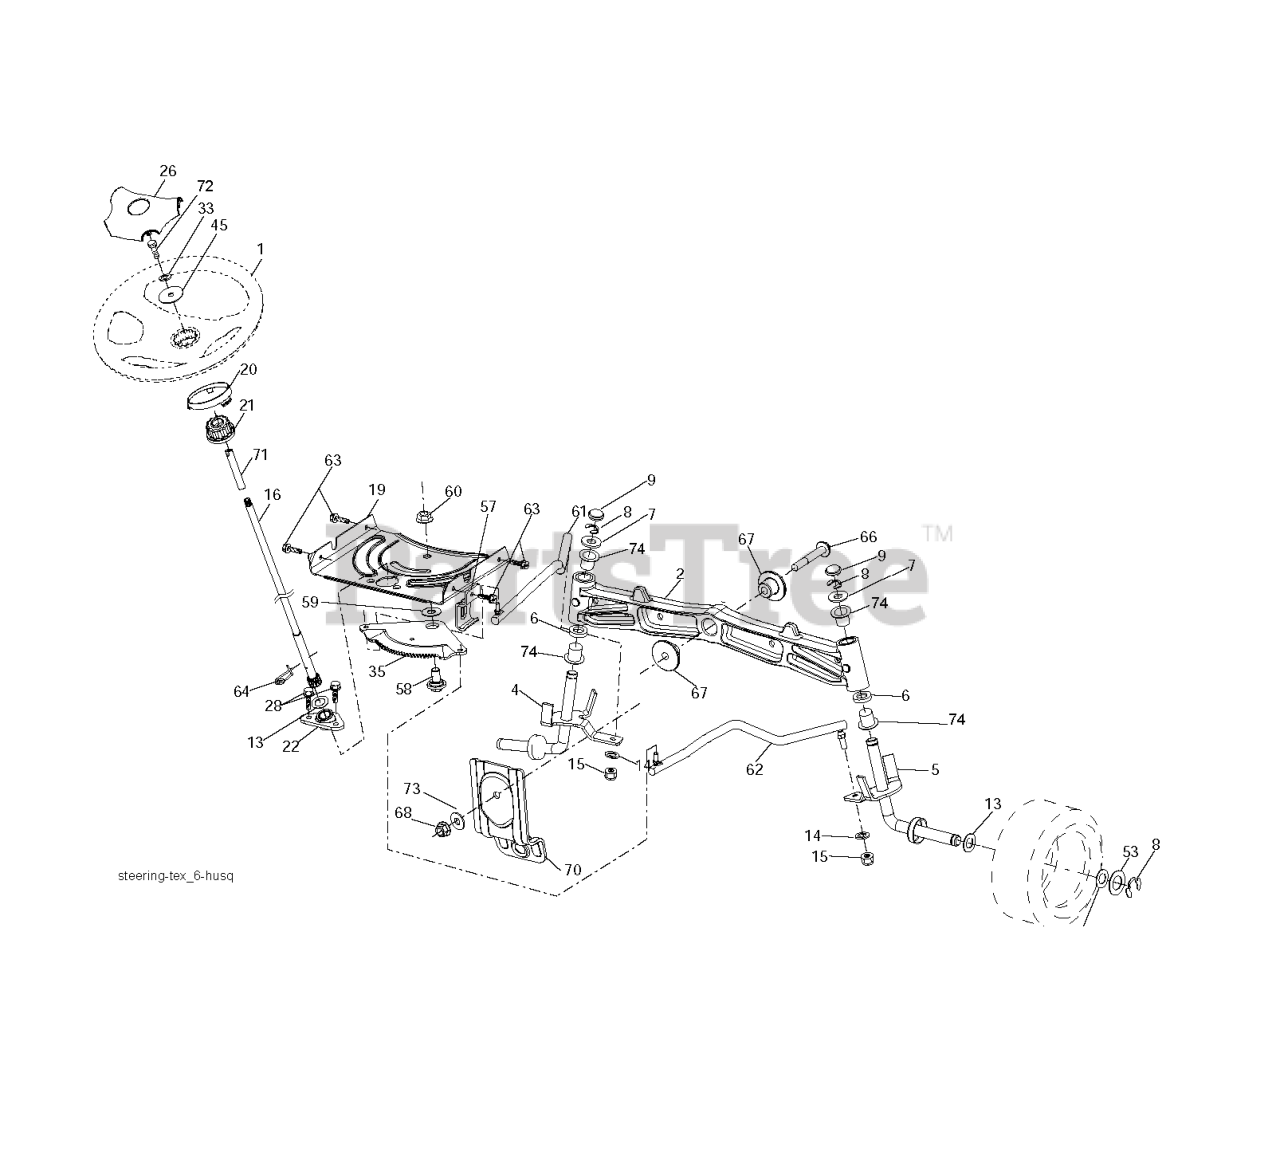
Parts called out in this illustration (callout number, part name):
1	STEERING WHEEL
2	AXLE.HALF.ASM.WELDED
4	SPINDLE.WELDED.LH.15"TEX
5	SPINDLE.WELDED.RH.15"T
6	THRUST WASHER
9	CAP.SPINDLE.BLACK
14	WASHER, LOCK 3/8
15	NUT CROWNLOCK 3/8-24
16	SHAFT STEERING
19	PLATE.STEER.DDL.NLT/NG
20	BOOT, STEERING
21	ADAPTER, WHEEL STNG..
22	BUSHING.ASM.STEERING.A
26	INSERT.CAP.STRG.WH.GRAY
28	SCREW, 3/8-16X3/4
33	WASHER.LOCK.HVY.HLCL.SPR.5/16
35	GEAR.SECTOR.PLATE.DDL.
45	WASHER.11/32
53	WASHER.HARDENED
57	BRACKET.UPSTOP.TEX
58	BOLT.SHOULDER.SECTOR.P
59	WASHER.THURST.SECTOR.S
60	NUT FLANGE LOCK 5/8-11
61	DRAGLINK.LH.BALLSTUD.D
62	DRAGLINK.RH.BALLSTUD.D
63	SCREW
64	RETAINER.CLIP.SPRING.S
66	BOLT HEX FGHD 7/16-14 X 3 SERR
67	BUSHING.PM.FRONT AXLE
68	NUT.LOCK.FLANGE.7/16
70	BRKT.DECK.SUSPENSION.F
71	SHAFT EXTENSION STEERING
72	BOLT YT
73	WASHER.1.5X.505X.118
74	BRNG T
